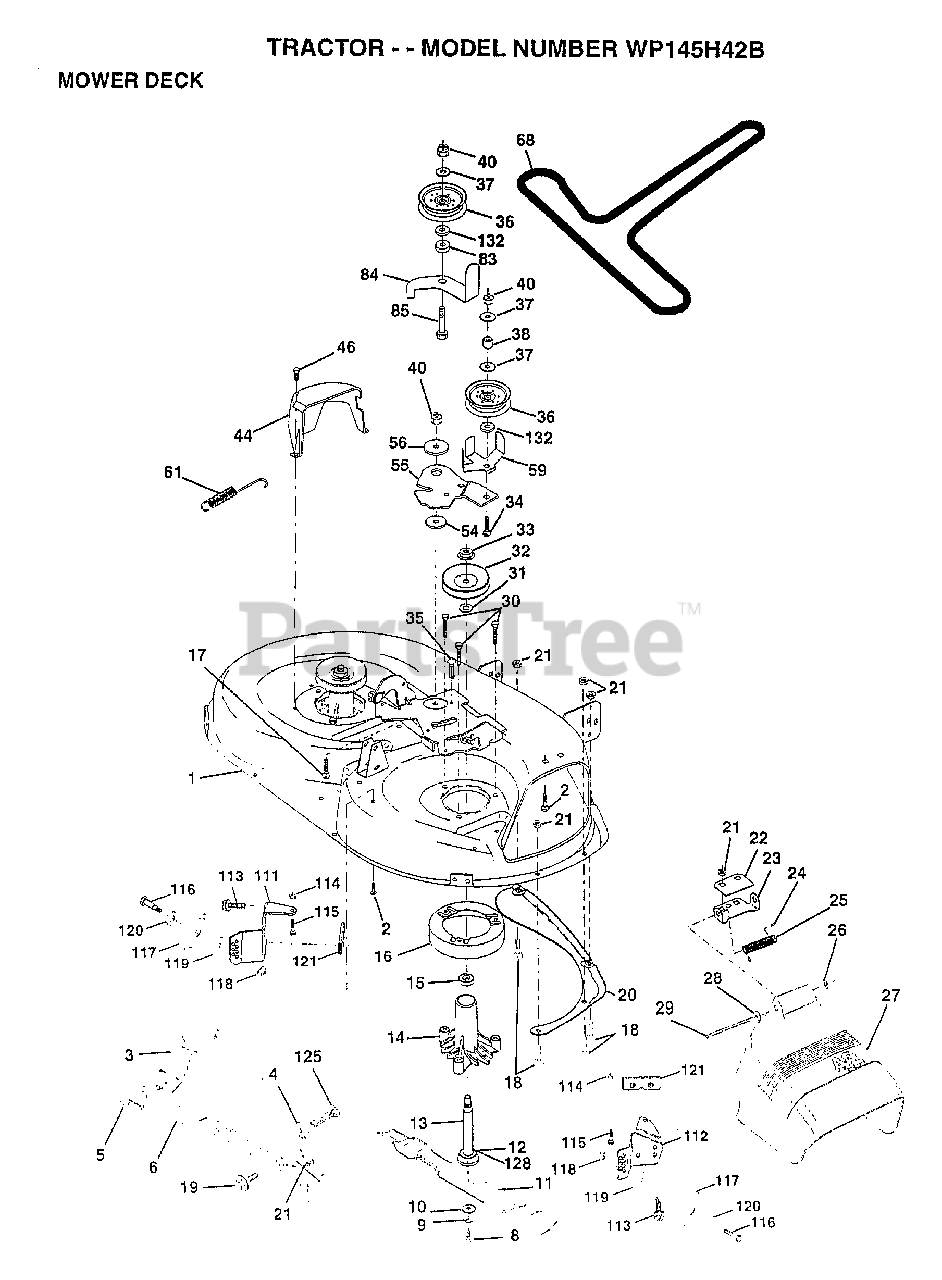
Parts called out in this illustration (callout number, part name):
1	DECK.WELD.42.
2	BOLT
3	BRKT ASM SWAY BAR
4	BRKT DECK SW BAR
8	BLADE BOLT
10	WASHER.HARD.BLADE
11	"BLADE.42"" HIPERF"
12	BEARING.BALL
14	HSG ASM MANDREL
15	BEARING
16	STRIPPER RND MWR
17	BOLT CARRIAGE
18	BOLT
19	BOLT SHD 5/16-18
22	STIFFENER BRKT
23	DEFLECTOR BRKT
24	CAP-SLEEVE LT
25	SPRING TORSION
26	NUT PUSH M
27	DEFLECTOR.SHIELD
28	WASHER
29	HINGE ROD
31	WASHER
32	PULLEY.MANDREL.42
34	BOLT
35	XMAS TREE FASTNER
36	FLAT IDLER PULLEY
37	WASHER
44	GUARD MAND LH BLK
46	SCREW.1/4-20X5/8
54	HARDENED WASHER
55	ARM-IDLER
56	SPACER RETAINER
59	GUARD IDLER TUV
61	SPRING.EXTENSION
68	BELT.V.T-PATH
83	WASHER
84	"KEEPER-BELT,FIXED"
85	BOLT RDHD 3/8-16
111	BRACKET.GWHL.LH.
112	BRACKET.GWHL.RH.
113	SCREW
116	BOLT M
117	WHEEL.GAGE.BLK.PL
118	LOCKNUT
119	WASHER
120	WASHER
121	BRACKET.EXTRD.GWL
125	COTTER PIN
128	WASHER.FELT.
132	WASHER GT
